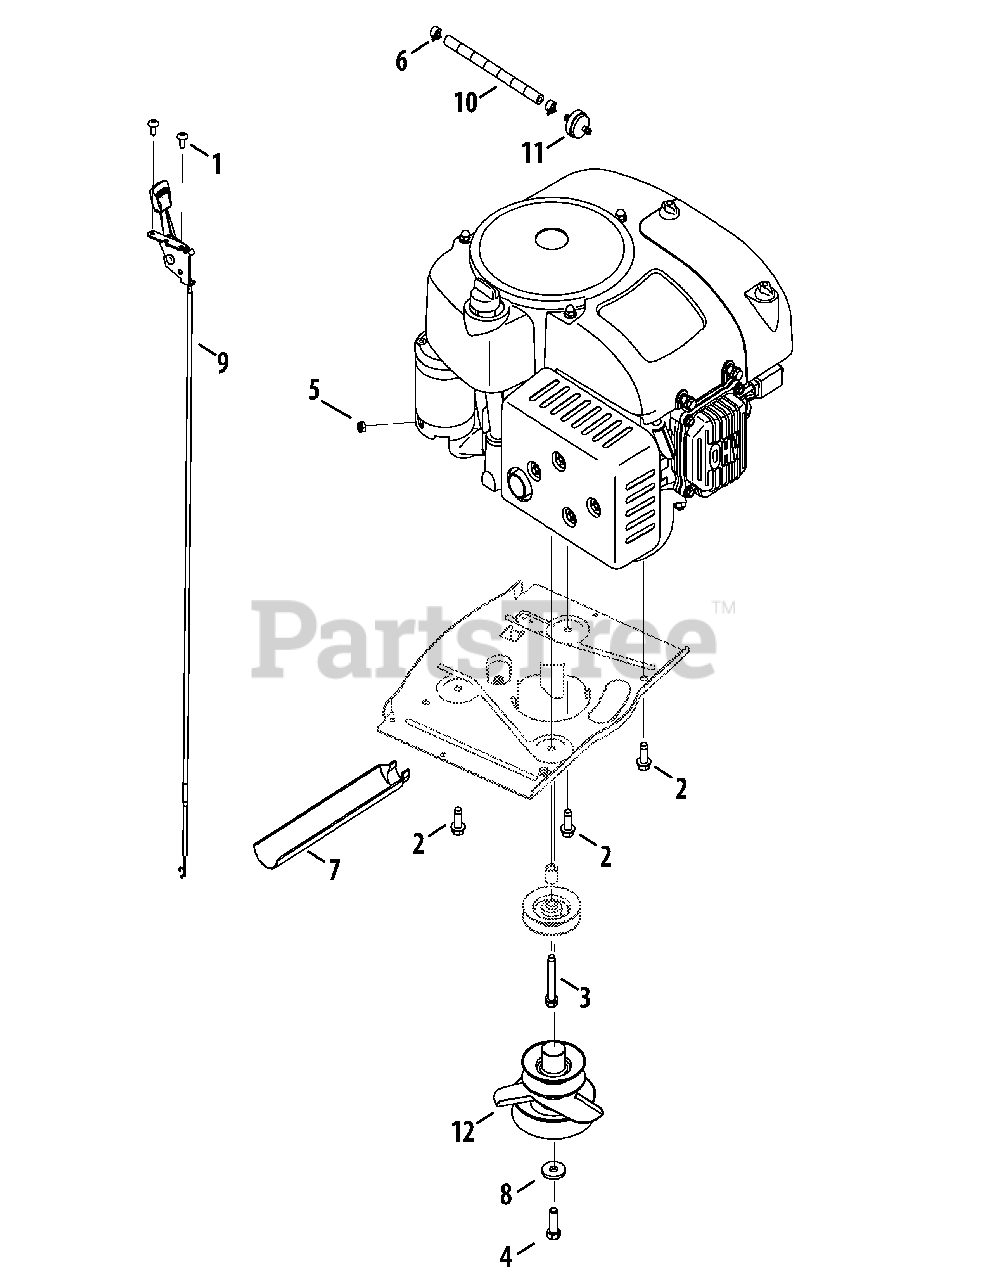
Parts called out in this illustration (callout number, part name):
1	Tap Screw, 1/4-20, 0.500
2	Tap Screw, 3/8-16, 1.000
3	Tap Screw, 3/8-16, 2.250
4	Hex Head Screw, 7/16-20 x 1.25
5	Hex Nylon L- Nut M6 x 1.0
6	Hose Clamp, .490 DIA.
7	Oil Drain Sleeve
8	Flat Washer, .450 x 1.25 x .164
9	Throttle/Choke Cable 31 Lg.
10	Low Permeation Fuel Line, 1/4
11	Fuel Filter
12	Engine Pulley, 4.46 / 3.39
